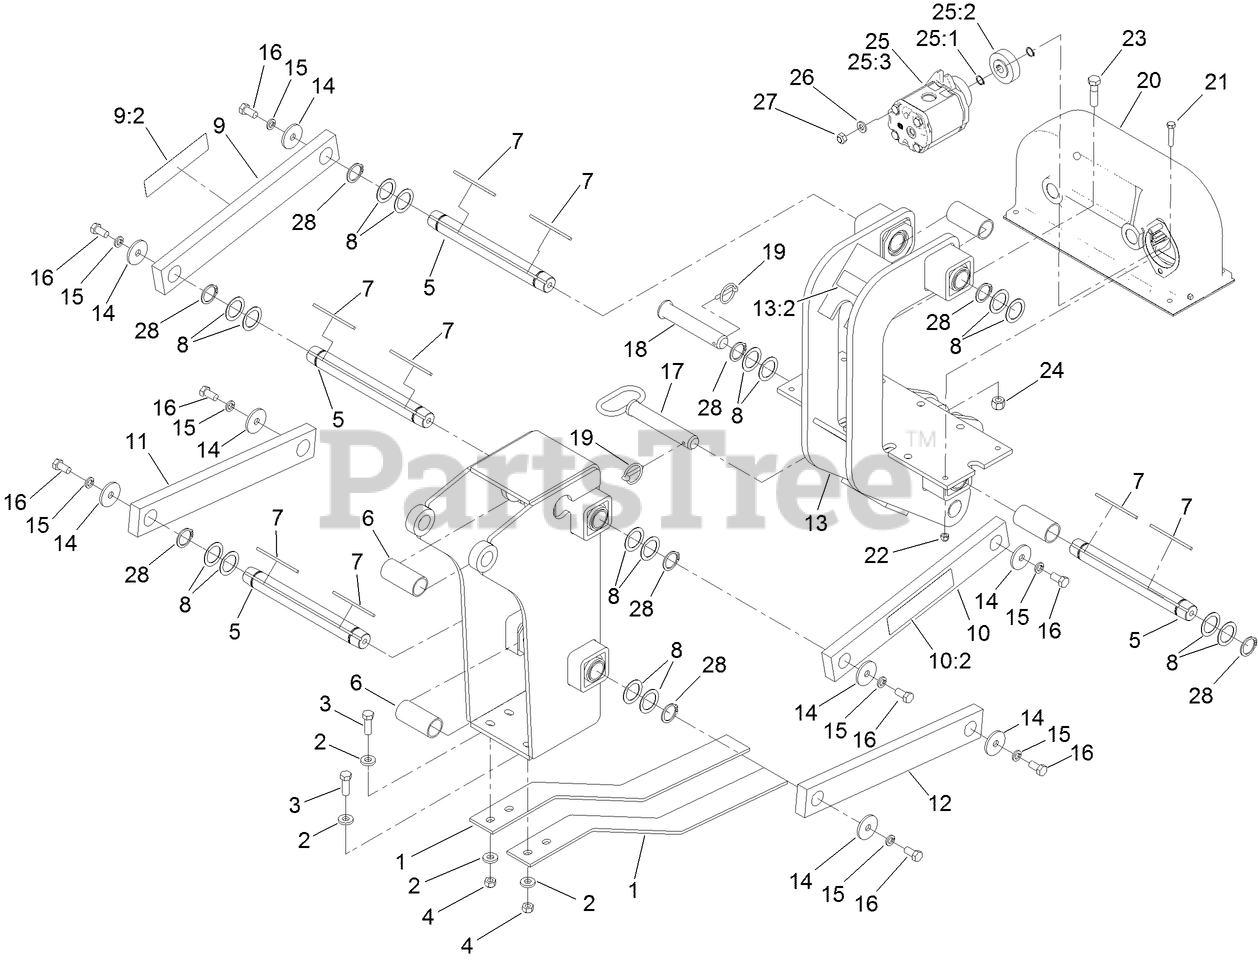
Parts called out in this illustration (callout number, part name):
1	SPRING-SHOE
2	WASHER-HARDENED
3	SCREW-HH
4	LOCKNUT
5	SHAFT-ARM, PLOW
6	TUBE-SPACER
7	KEY-SQUARE
8	SHIM-ARM
9	RH UPPER BAR AND DECAL ASM
9:2	DECAL-DANGER, PLOW
10	LH UPPER BAR AND DECAL ASM
10:2	DECAL-DANGER, PLOW
11	ARM-PLOW, LOWER (RH)
12	ARM-PLOW, LOWER (LH)
13	BLADE-MOUNTING W DECAL
13:2	DECAL-DANGER
14	WASHER-THRUST
15	WASHER-LOCK
16	SCREW-HH
18	PIN-MOUNTING, BLADE
19	KLIK PIN ASM
20	GEAR CASE ASM
21	SCREW-HH
22	NUT-HEX
24	NUT-HEX
25	HYD GEAR MOTOR ASM
25:1	RING-RETAINING
25:2	GEAR-MOUNTING, DRIVE
25:3	GEAR MOTOR ASM
26	WASHER
27	NUT-HEX
28	RING-RETAINING
